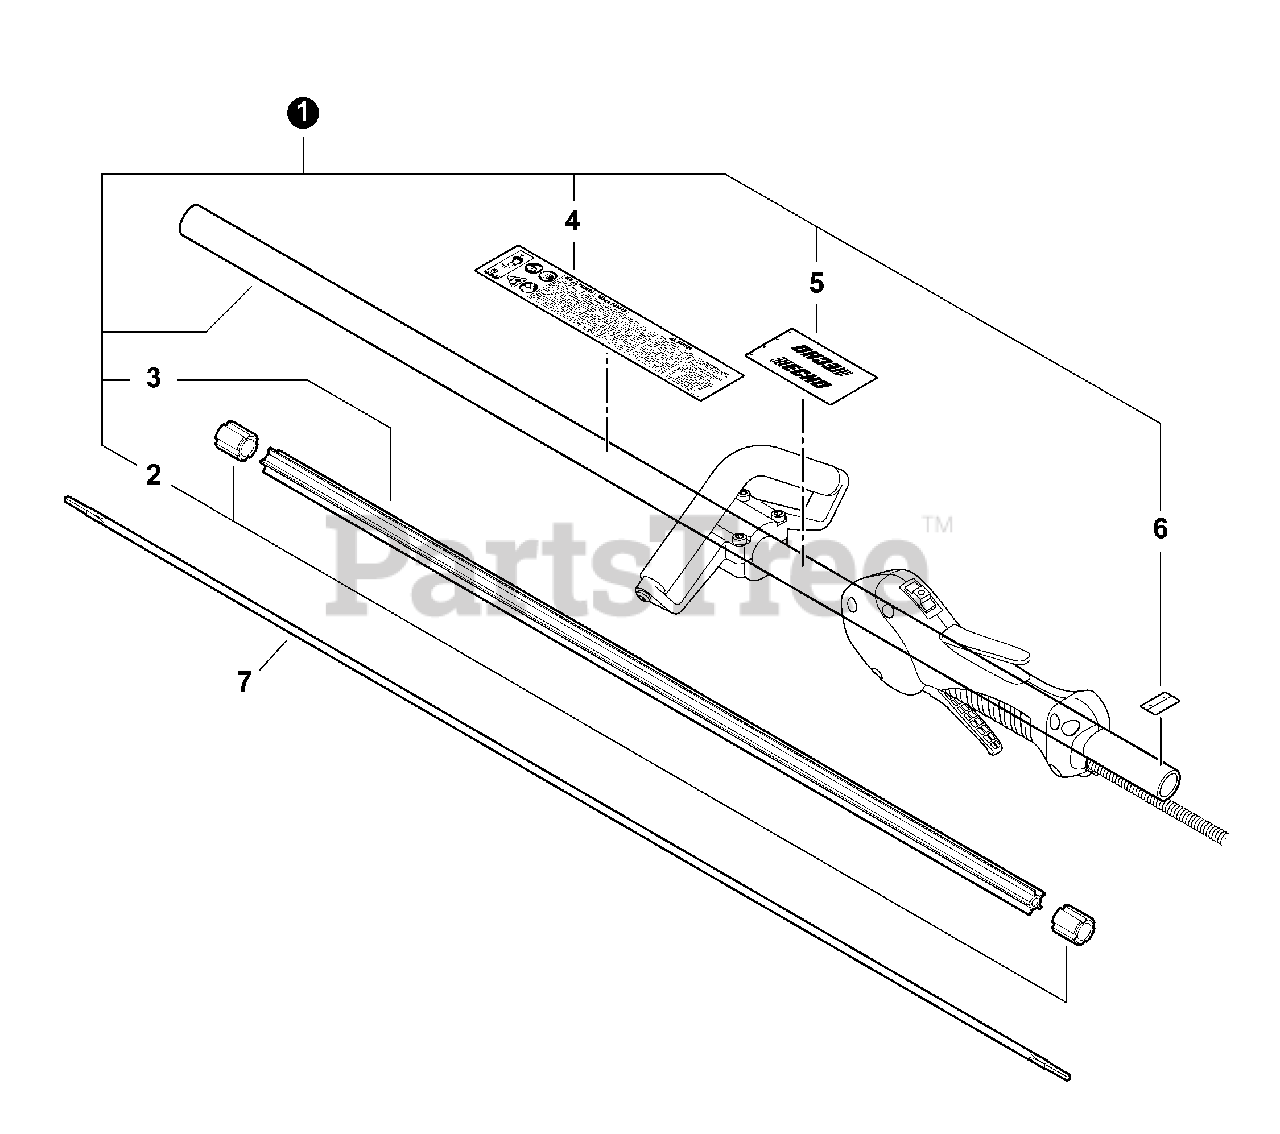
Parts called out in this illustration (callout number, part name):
1	MAIN PIPE ASSY
3	LINER - FLEXIBLE
4	LABEL - CAUTION
5	LABEL - HANDLE LOCATION
6	LABEL - ALIGNMENT
7	DRIVESHAFT - FLEXIBLE
